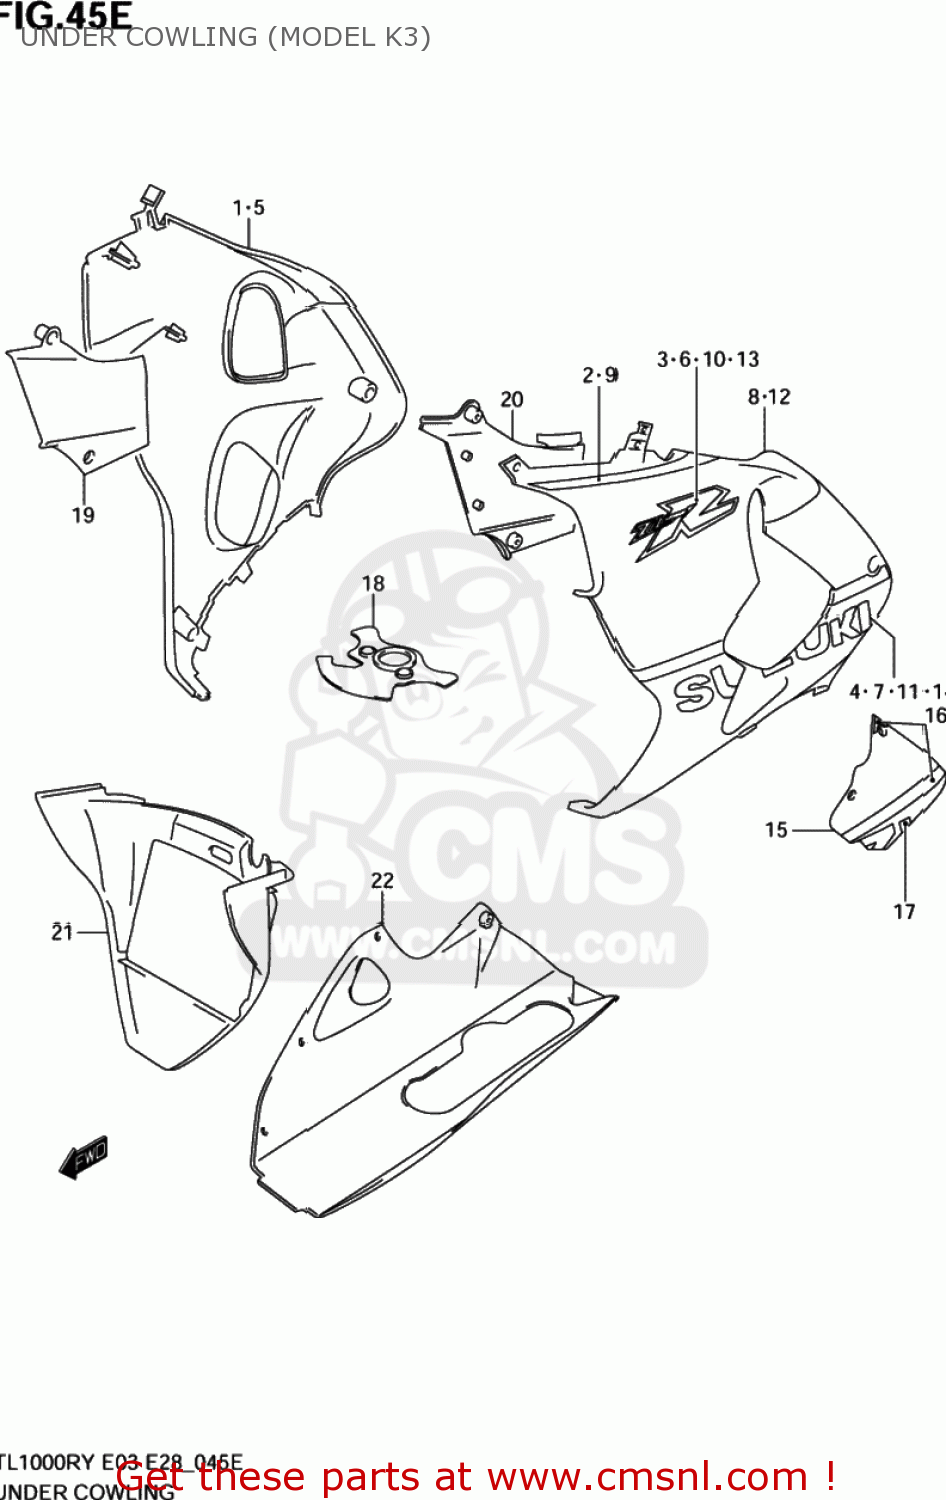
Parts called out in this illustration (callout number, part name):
1	COWLING ASSY,UNDER,R
2	TAPE,COWL UNDER UPR,R
3	EMBLEM,COWLING UNDER,TL1000R
4	EMBLEM,UNDER,SUZUKI,R
5	COWLING ASSY,UNDER,R
6	EMBLEM,COWLING UNDER,TL1000R
7	EMBLEM,UNDER,SUZUKI,R
8	COWLING ASSY,UNDER,L
9	TAPE,COWL UPR,L
10	EMBLEM,COWLING UNDER,TL1000R
11	EMBLEM,UNDER,SUZUKI,L
12	COWLING ASSY,UNDER,L
13	EMBLEM,COWLING UNDER,TL1000R
14	EMBLEM,UNDER,SUZUKI,L
15	LID ASSY,COWL UNDER,L
16	TAPE SET,LID COWL UNDER,L
17	TAPE,COWL LID,L(WHITE)
18	COVER,LWR BRACKET
19	COWLING,UNDER INNER,R
20	COWLING,UNDER INNER,L
21	COWLING,UNDER CTR
22	COWLING,UNDER RR
